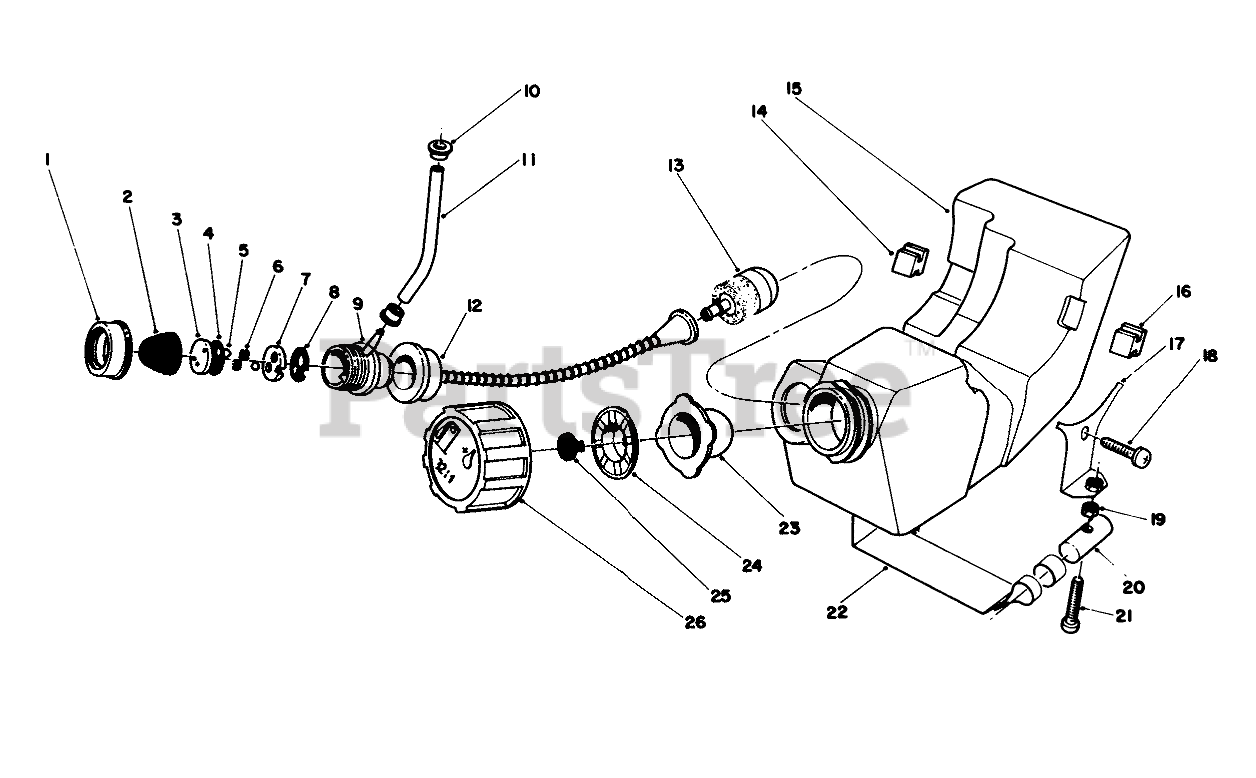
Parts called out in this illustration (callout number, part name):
1	PUMP CAP
3	SEAT VALVE
4	GASKET
6	SPONGE
7	SEAT VALVE
8	GASKET
9	Primer Pump Assembly (Incl. Ref. #1-8)
11	TUBE, FUEL
12	SUCTION HOSE
13	Filter-Fuel
15	Fuel Tank Assembly (Incl. Ref. #1-9, 12,13, 23-26)
17	Hanger-Tank
18	Screw
21	Screw
22	BAND, TANK
23	GASKET - PACKING
24	HOLDER
25	BREATHER VALVE
26	TANK CAP
